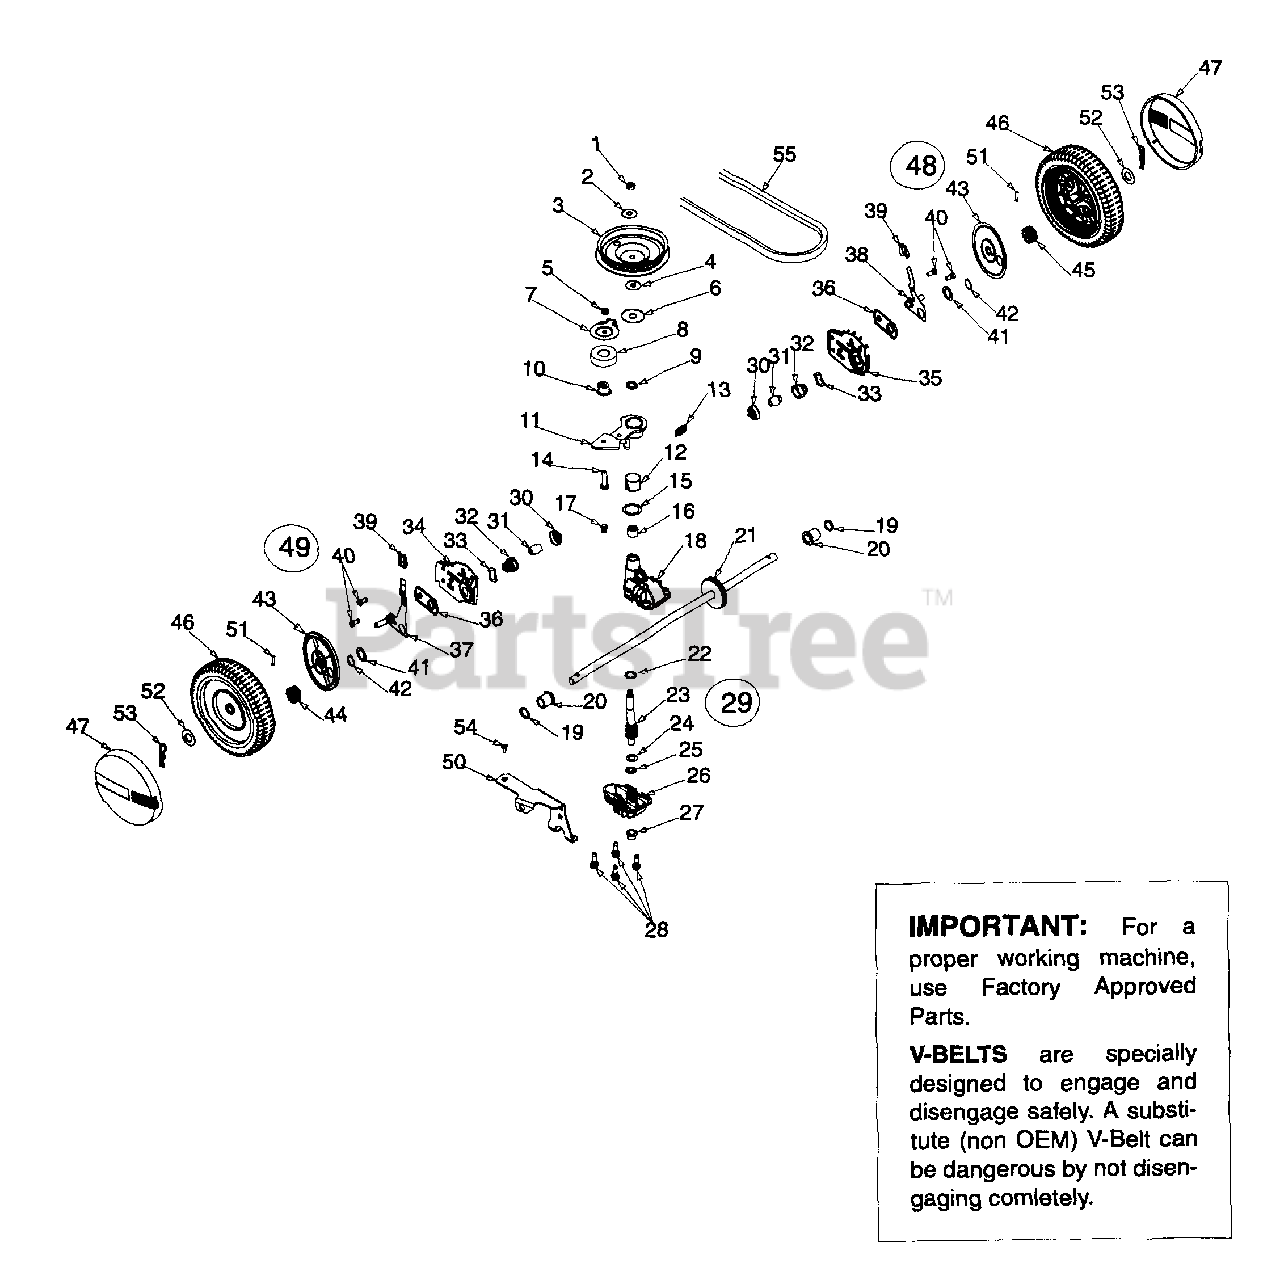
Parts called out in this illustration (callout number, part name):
1	Hex Jam Nut 5/16-24
2	Bell Wash .325 x .930 x .045
3	Pulley
4	Bell Wash .325 x .930 x .045
5	Hex Nut 1/4 - 28 Lock
6	Flat Wash .442 x 1.38 x .060
7	Belt Keeper
8	Ball Bearing
9	Oil Seal
10	Flange Spacer
11	Idler Bracket Ass'y
12	Bearing Sleeve
13	Wash: Flat:.504 x .700 x .030
14	Hex Cap Screw 1/4-28 x 1.00 Gr. 5
15	Flat Washer .865 x 1.145 x .030
16	Needle Bearing .438 x .625 x .500
17	Plug 1/4 x .437
18	Housing Asm:Upper:
19	Seal:Oil: .500 x .687 x .094
20	Flange Bearing .503 x .689 x .792
21	Output Shaft
22	Flat Washer .504 x .700 x .030
23	Pinion Shaft 10T.
24	Thrust Washer .375 x .70 x .030
25	Thrust Washer .388 x .625 x .062
26	Housing:Lwr:
27	Flange Bearing .378 x .531 x .370
28	Hex Screw w/Wash 1/4-20 x .750
29	Transmission-Complete
30	Bearing Retainer
31	Bearing Sleeve .50 I.D.
32	Bearing Support
33	Wave Washer 1.5 x 1.0 x .029
37	Front Lever R.H
38	Front Lever L.H.
39	Knob
40	Hex Cap Screw 3/8-16 x .75
41	Washer DD 1.5" O.D.
42	Snap Ring 1.0 Dia
43	Wheel Dust Cap
44	Gear 14T RH Fwd
45	Gear 14T LH Fwd
46	Whl:Compl:8 x 2 Link Grey Fwd
47	Hubcap: Whl: Radial Spoke Grey
48	Height Adj. Complete RH
49	Height Adj. Complete LH
50	Cable Idler Bracket
51	Dowel Pin
52	Flat Washer 1/2 x 1.00 x .063
53	Cotter Pin .08 x 1.42
54	Screw, Shoulder .375 x .25AB: 1/4-20 Thd.
55	"V" - Belt
